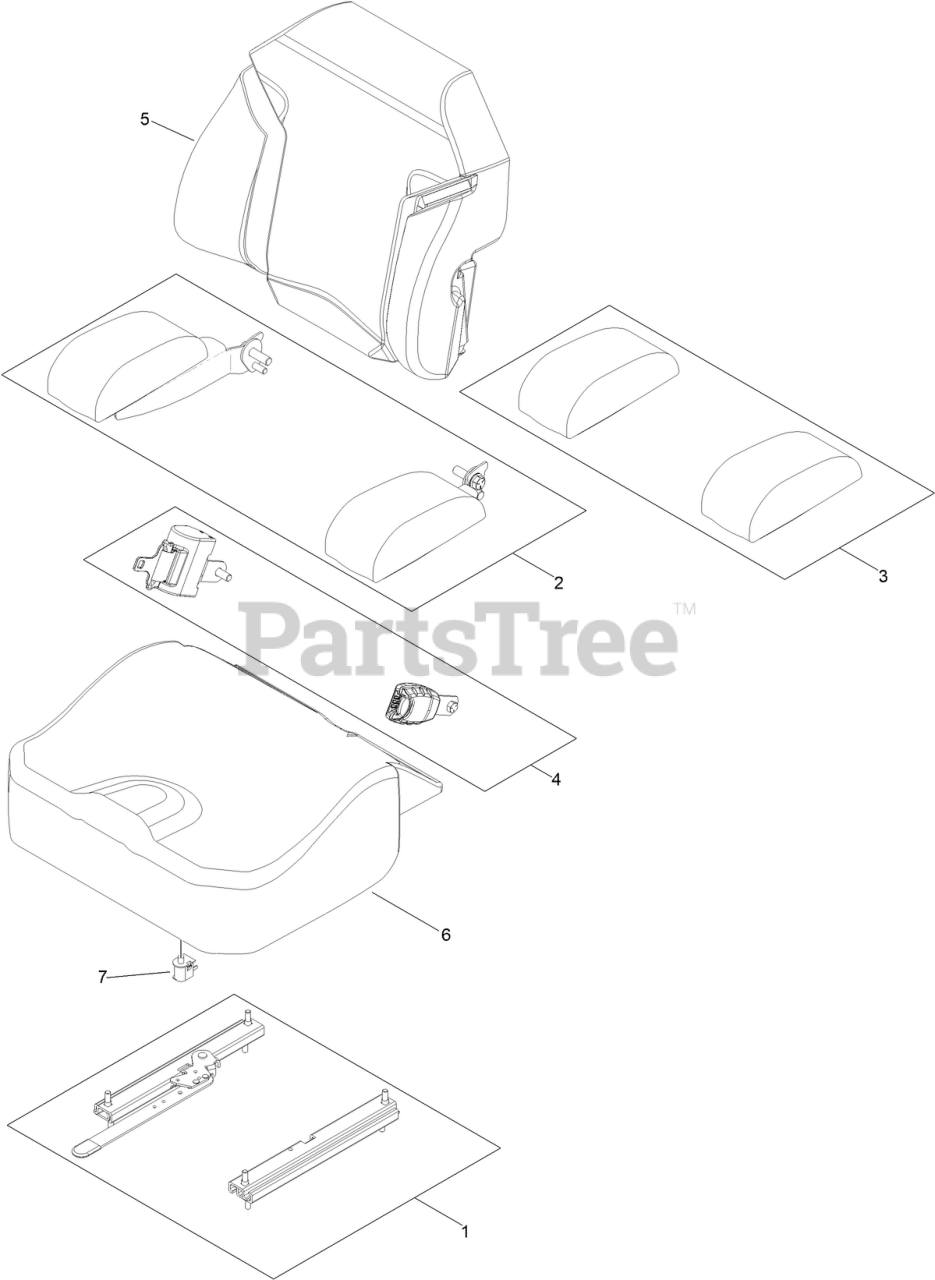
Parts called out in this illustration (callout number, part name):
1	SEAT TRACK SET
2	ARMREST KIT
3	PADS-ARMREST
4	SEAT BELT KIT
5	COVER-BACK, SEAT
6	COVER-BOTTOM, SEAT
7	SWITCH-BAIL
